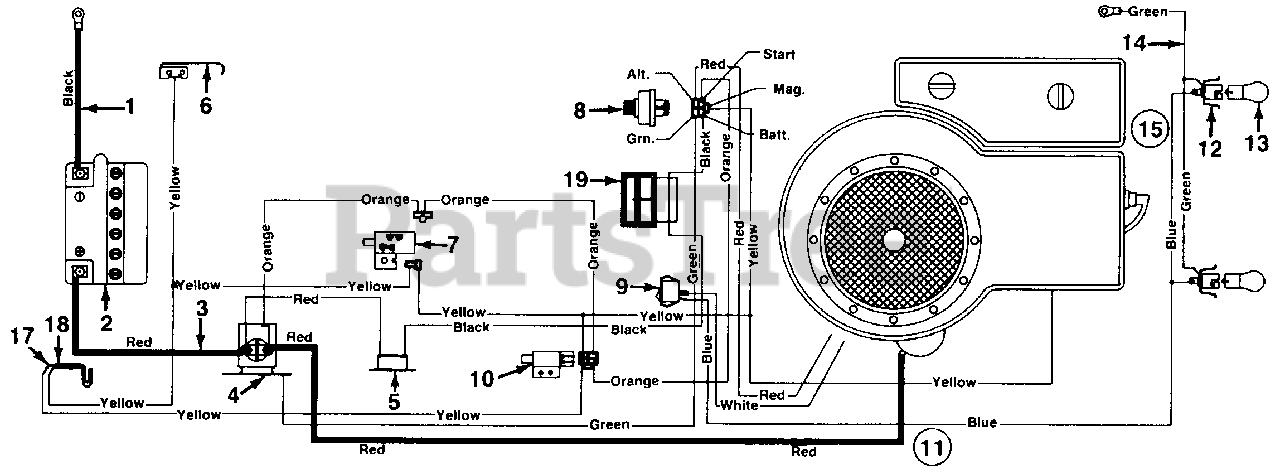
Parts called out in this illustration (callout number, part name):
1	Ground Wire
2	Battery
3	Electric Wire-8.0" Lg.
4	Solenoid
5	Circuit Breaker
6	Spring Switch
7	Safety Switch
8	Ignition Switch
9	Light Switch
10	Safety Switch
11	Harness
12	Socket
13	Bulb
14	Ground Wire
15	Headlight Harness
17	Safety Switch
18	Safety Switch
19	Ammeter
